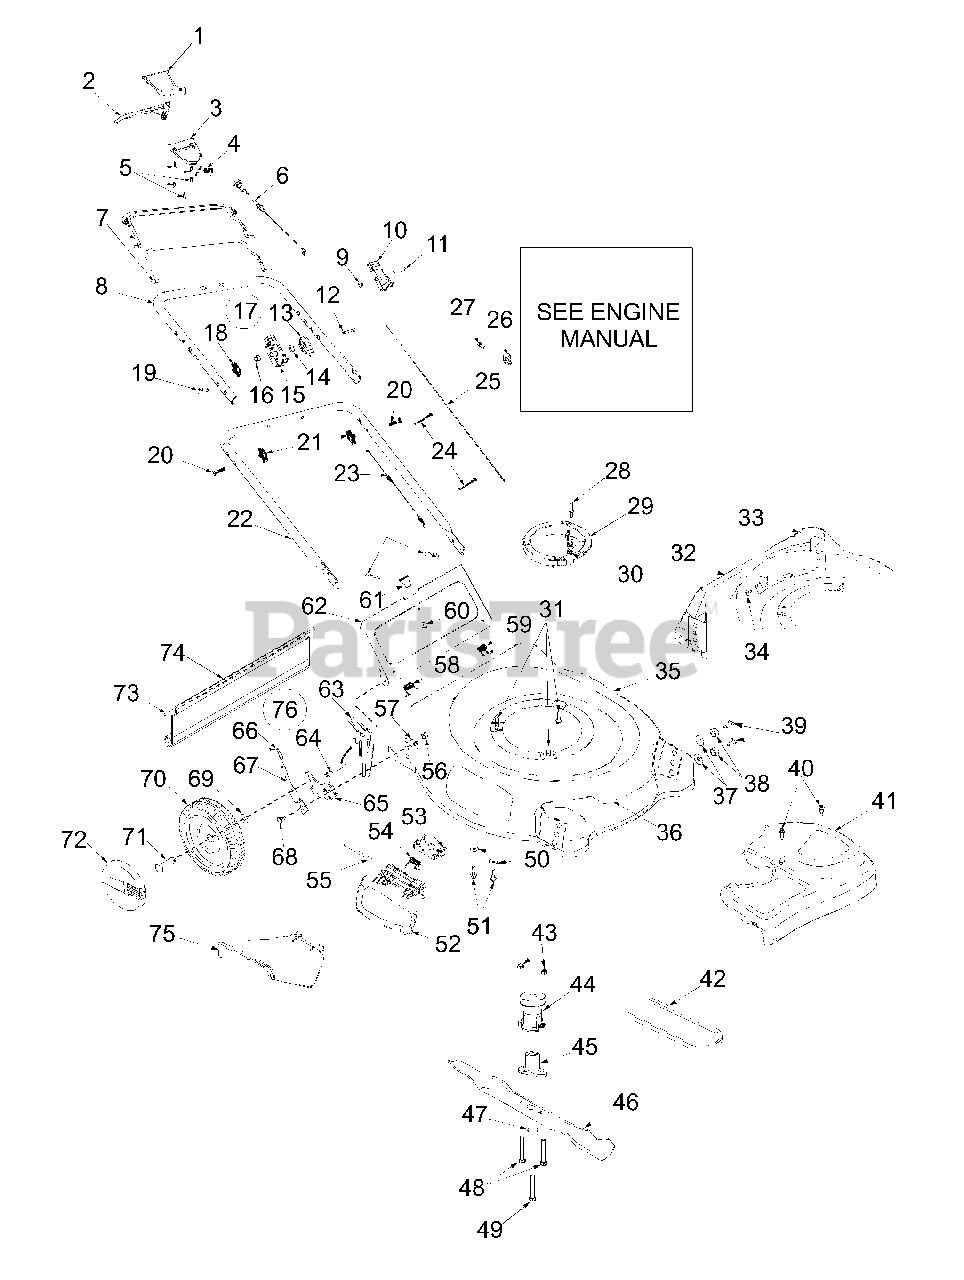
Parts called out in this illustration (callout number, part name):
1	Upper Drive Cover
2	Drive Lever
3	Lower Drive Cover
4	Mounting Cap
5	Screw #10-12:75
6	Drive Cable
9	Hex Lock Nut 1/4-20
10	Throttle Hsg. w/o Lever
11	Scr. Oval C-Sunk 1/4-20 x 1.31
12	Scr. Oval C-Sunk 1/4-20 x 1.81Scr. 1/4-20
13	Throttle Lever
14	Curved Washer .663 x .980 x .014
15	Throttle Housing
16	Hex Lock Nut 1/4-20 Thd.
17	Throttle Body Comp.
19	Eye Bolt 1/4-20
20	Carriage Bolt 5/16-18 x 2.0
21	Knob
23	Throttle Cable: 55" B&S
24	Tie Cable
25	Control Cable 39" B&S
26	Cable Clamp B&S
27	Hex Screw: T: #10-32 x .625 Lg. (B&S)
28	Pin-Belt Keeper
29	Engine Spacer
30	Hex Nut 1/4-20 Thread
31	Tapp Screw w/Hex Lock Wash
34	Scr. AB: 1/4-14 .625 Trust
38	Bell Washer .39 x 1.13 x .062
39	Hex Screw 3/8-16 x .75
40	Screw #12 x .457
41	Trans Cover - Black
42	V-Belt
43	Hex Lock Nut 1/4-20 Thd.
44	Drive Pulley
45	Blade Adapter Kit
46	21" Mulching Blade w/star
47	Bell Washer .396 x 1.140 x .095
48	Hex Screw 1/4-2 0x 1.50
49	Hex Screw 3/8-24 x 2.50
50	Bell Washer .265 x .75 x .062
51	Tapp Screw 1/4-20 x .500
52	Mulch Plug Ass'y
54	Torsion Spring
55	Hinge Pin
56	Hex Nut 3/8-16
57	Bell Washer .39 ID x 1.38 OD
58	Torsion Spring - RH
59	Torsion Spring - LH
60	Scr. Tr. Mach #10-24 x .380
64	Hex Scr. w/wash. 1/4-14 x .62
65	Pivot Bar - RH
66	Knob
67	Spring Lever
68	Shldr Scr. .500 Dia x .434 Long
69	Bell Washer .380 x .880 x .062
70	Wheel 8 x 1.75 Disk Bar Grey
71	Shldr. Scr. .498 x 1.445
72	Hubcap: Euro Grey
73	Wire
74	Rear Flap
75	Chute Deflector
